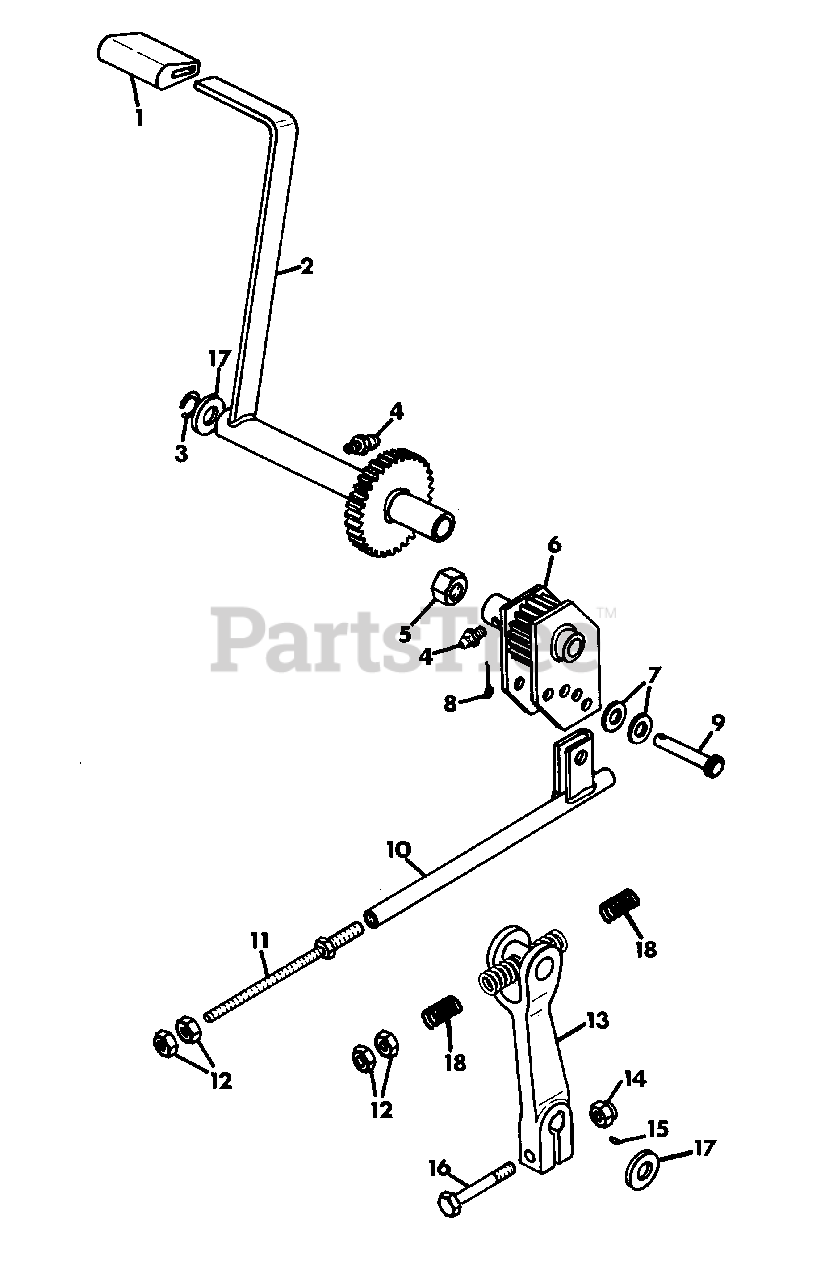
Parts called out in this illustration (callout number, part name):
1	GRIP, HANDLE
2	LEVER, FWD-REV
3	RING, RETAINING .750 SHAFT
4	FITTING, LUB 1/4-28
5	NUT, LOCK 5/8-11
6	WELDMENT, ARM FWD-REV
7	WASHER, FLAT .406X.812X.065
8	PIN, COTTER .09X.75
9	PIN, CLEVIS .375X1.531
10	WELDMENT, FWD-REV ROD
11	ROD, CONTROL EXTENSION
12	NUT, JAM 3/8-16
13	LEVER, CONTROL
14	NUT, LOCK 5/16-18
15	KEY, WOODRUFF .125X.625 HARD
16	BOLT, HEX 5/16-18X2.00
17	WASHER, FLAT .812X1.496X.134
18	SPRING
